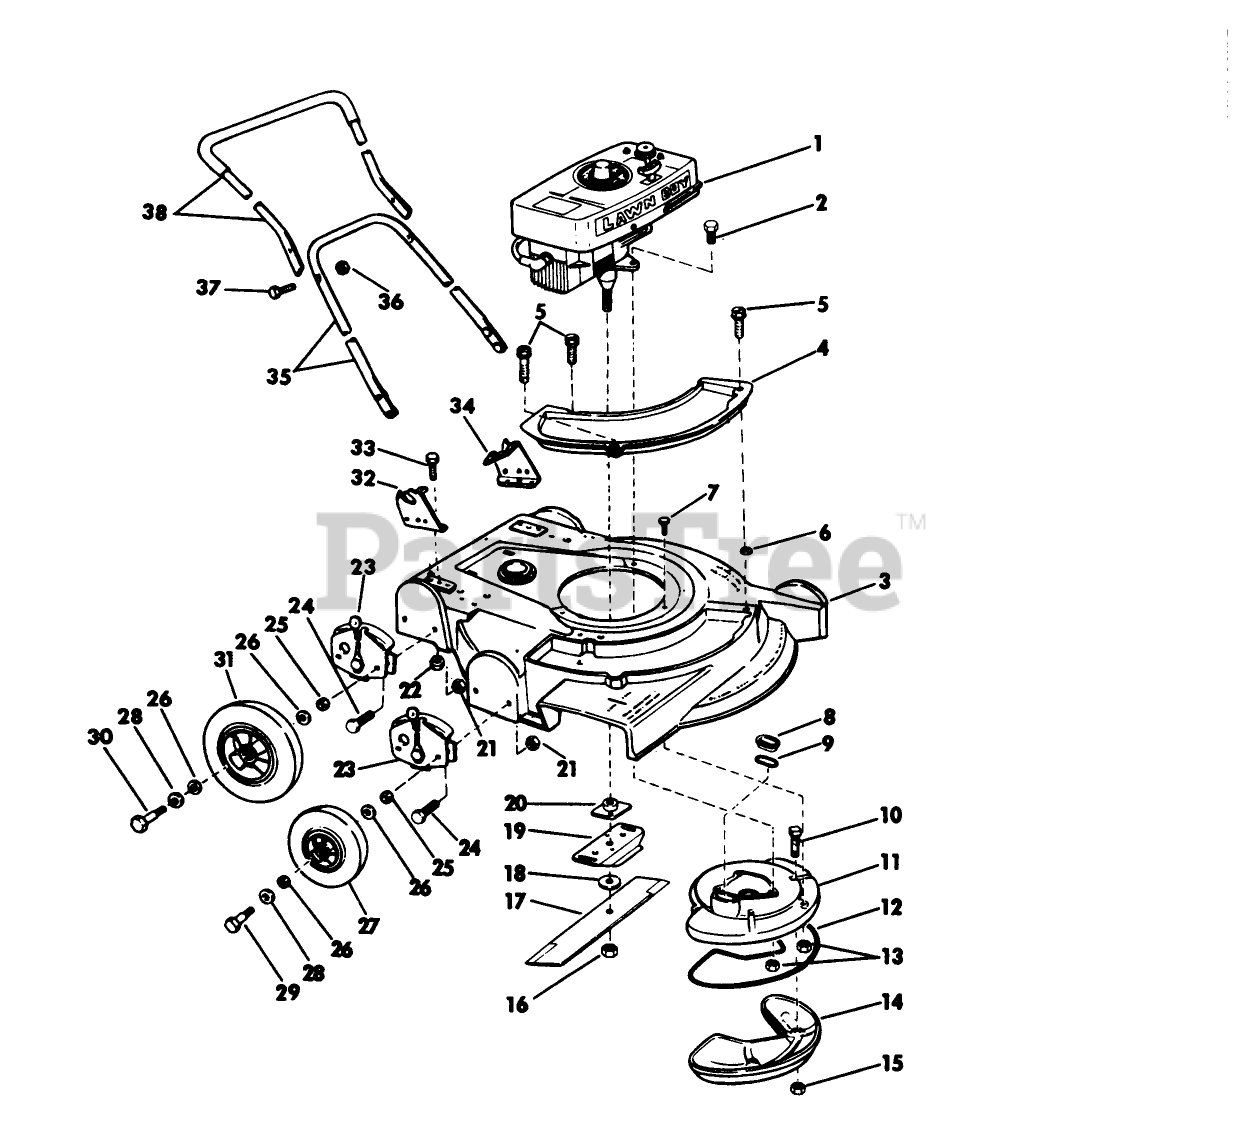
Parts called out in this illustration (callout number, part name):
5	SCREW SEMS TRM HEX HD
7	SCREW
8	SLEEVE
9	GASKET S
13	NUT
15	LOCKNUT E
16	NUT-BLADE
18	WASHER
20	PLATE AND COLLAR ASM
21	NUT
22	NUT
25	WASHER WROUGHT
26	WASHER
27	WHEEL & TIRE KIT
28	SPACER
29	BOLT WHEEL
30	BOLT
35	HANDLE
37	SCREW
38	Handle Grip Assy. Top
